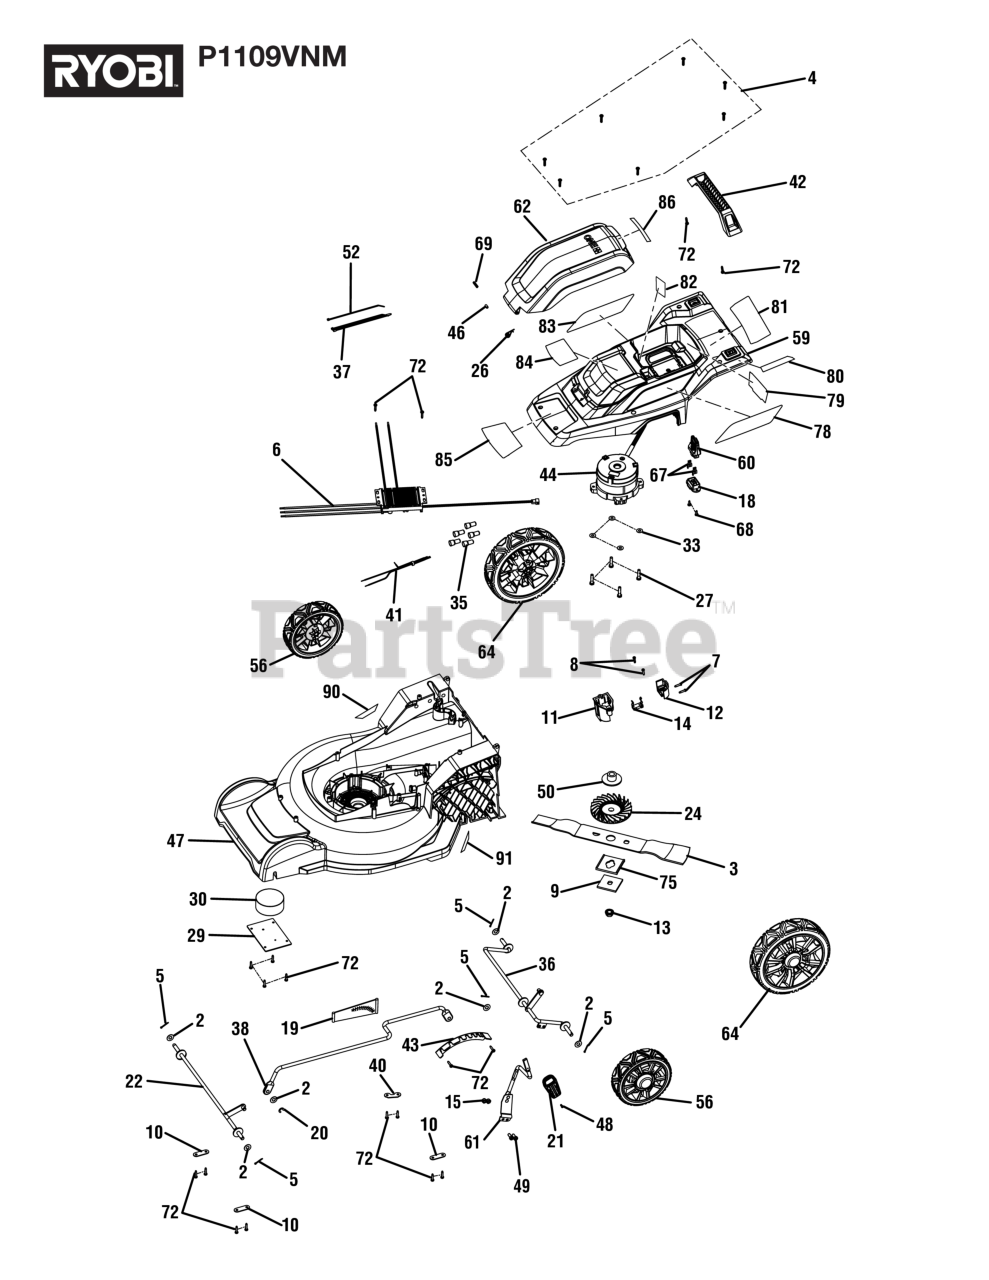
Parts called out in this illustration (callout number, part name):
2	Washer (ID8.4 x OD18 x 1t)
3	16 in. Blade
4	Screw (M4 x 20 mm, T20 Torx Pan Hd. S.T.)
5	Cotter PinÏ? (2.5)
6	Circuit Board Assembly
7	Screw (M4 x 16 mm, T20 Torx Socket Pan Hd.)
8	Screw (M4 x 16 mm, T20 Torx Socket Pan Hd.)
9	Metal Blade Retainer
10	Axle Pressure Plate
11	Base (Battery Connect)
12	Press Cover (Battery Connect)
13	Blade Nut (M10 x 1.25, Hex Flange Hd.)
14	Battery Contact Holder Assembly
15	Lock Nut (M6 x 6 mm)
18	Key Holder
19	Dust Proof Plate
20	Retaining Ring (E)
21	Height Adjustment Knob
22	Front Wheel Axle
24	Fan Blade Adapter
26	Torsion Spring
27	Bolt (M6 x 26 mm, Hex Hd.)
29	Metal Plate
30	Weight Plate
33	Washer (ID6.2 x OD15 x 0.08t)
35	Wire Connector
36	Rear Wheel Axle
37	NYLON CABLE TIE
40	Axle Press Plate
41	Inner Wire
46	Battery Door Axle
47	Deck Assembly
48	Screw (M3 x 9 mm, Flat Hd.)
49	Screw (M6 x 14 mm, Hex Soc. Hd.)
50	Motor Shaft Bushing
52	Cable Ties
56	6 in. Wheel Assembly
59	Top Cover Assembly (Inc. Key Nos. 78-85)
60	Start Key
61	Height Adjustment Handle
62	Battery Cover (Inc. Key No. 79)
64	8 in. Wheel Assembly
67	Female Terminal
68	Screw (M4.2 x 12 mm, T20 Torx Pan Hd.)
69	Compression Spring
72	Screw (M4 x 18 mm, T20 Torx Pan Hd.)
78	HP Logo Label (Left)
79	Start Key Warning Label
80	Deck Height Adjustment Label
81	Danger (ENG/FR)/Warning Label (Trilingual)
82	Data Label
83	HP Logo Label (Right)
84	Warning Label (SP)
85	Front Logo Label
86	Icon Label
90	16 in. Callout Label (Right)
91	16 in. Callout Label (Left)
